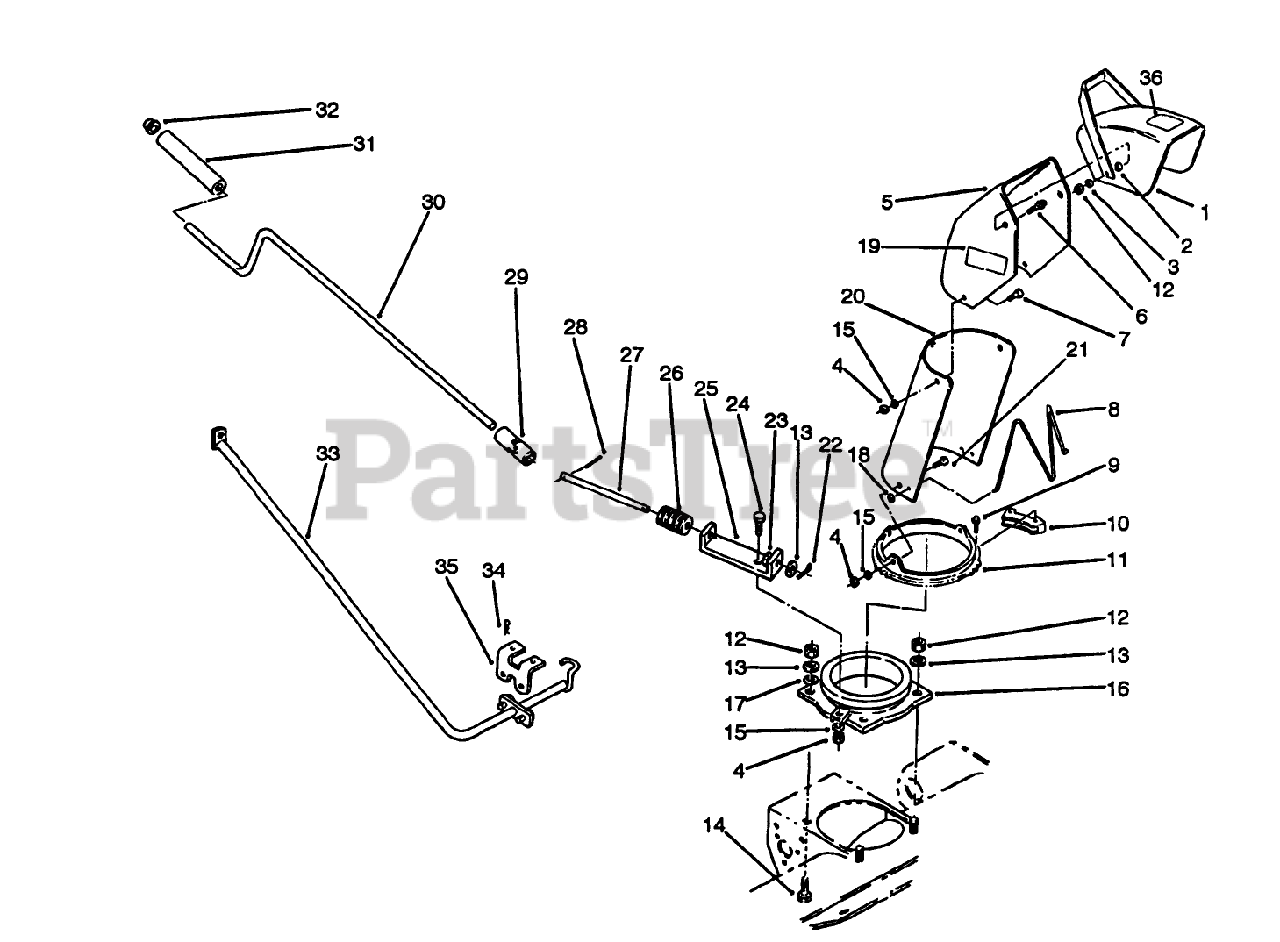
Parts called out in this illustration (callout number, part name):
1	Deflector (Incl. Ref. #36)
2	WASHER-RUBBER
3	WASHER-BELLEVILLE
4	NUT-LOCK, NI
5	Chute-Discharge (Incl. Ref. #19)
6	BOLT-CARR
7	SCREW-HH
8	WIRE-CHUTE
9	SCREW-SPECIAL
10	RETAINER-CHUTE
11	Ring-Swivel
12	NUT-LOCK, NI
13	WASHER-FLAT
14	SCREW-HH
15	WASHER-PLAIN
16	Adapter
17	WASHER
18	NUT-PUSH
19	Decal-Danger
20	Chute-Extender
21	BOLT-CARR
22	PIN-COTTER
23	WASHER-SPRING
24	BOLT-CARR
25	Bracket-Worm
26	GEAR-WORM, CHUTE
28	PIN-SPRING
29	Universal
30	ROD-CHUTE CONTROL
31	GRIP-CONTROL, CHUTE
32	RETAINER-PUSH ON
33	WLDMT-CRANK SPT R
34	PIN-HAIR
35	Bracket
36	Decal-Danger
